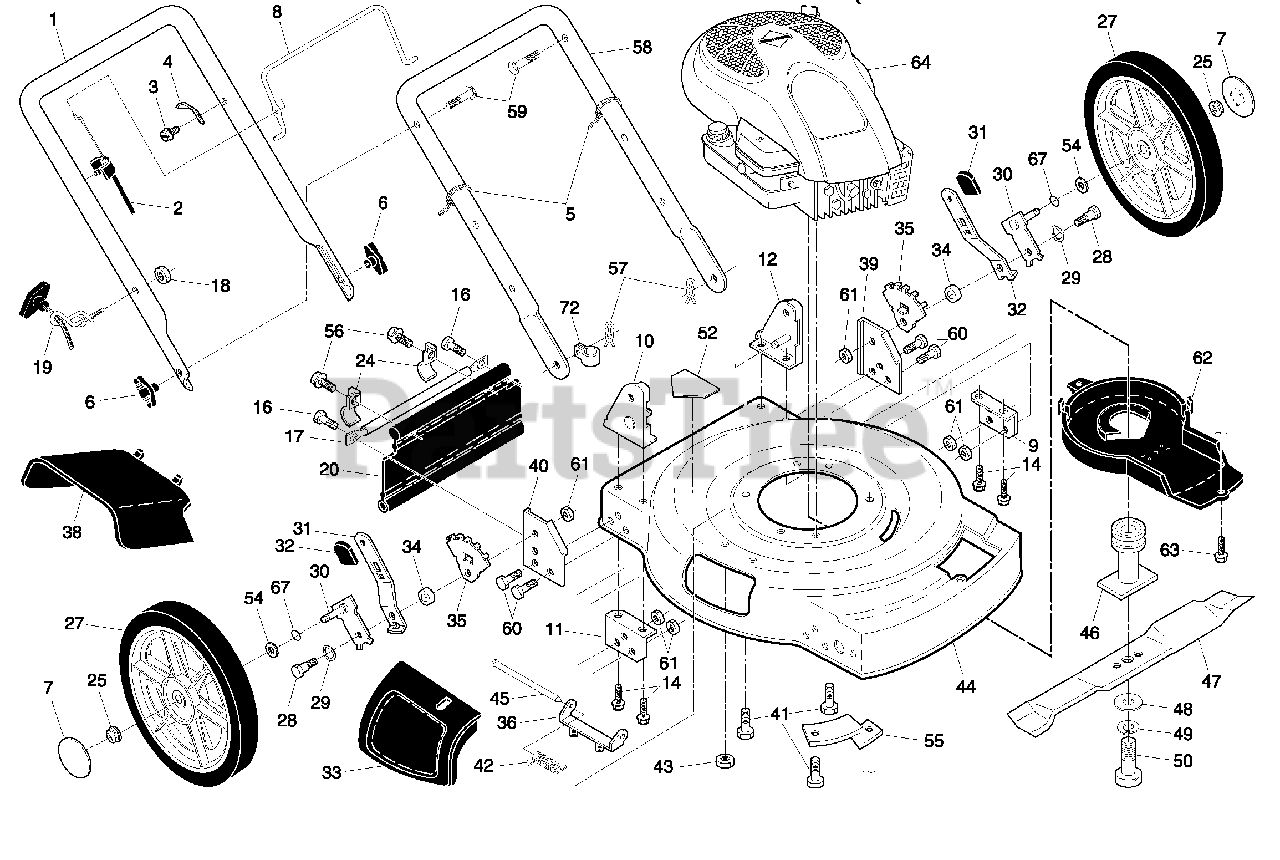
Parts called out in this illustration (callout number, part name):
1	Upper Handle
2	Engine Zone Control Cable
3	Screw
4	Bracket, Upstop
5	Wire Tie
6	Handle Knob
7	Hubcap
8	Control Bar
9	Support Bracket, Handle, LH
10	Handle Bracket, RH
11	Support Bracket, Handle, RH
12	Handle Bracket, LH
14	Screw, Thread Cutting 5/16-18 x 3/4
16	Screw
17	Support Rod
18	Locknut, Keps
19	Rope Guide
20	Rear Skirt
24	Clamp, Rear Skirt
25	Locknut, Hex 3/18-16
27	Wheel & Tire Assembly
28	Shoulder Bolt
29	Washer, Curved, Cylindrical
30	Axle Arm Assembly
31	Knob, Selector
32	Spring, Selector
33	Mulcher Door
34	Spacer
35	Bracket, Wheel Adjuster
36	Bracket, Housing
38	Deflector, Discharge
39	Support Bracket, LH
40	Support Bracket, RH
41	Screw, Hex Head, Threaded, Rolled 3/8-16 x 1-1/8
42	Spring, Torsion
43	Locknut, Hex
44	Kit, Lawn Mower Housing
45	Rod, Hinge
46	Blade Adapter / Pulley
47	Blade, 22"
48	Washer, Hardened
49	Washer, Lock, Helical
50	Screw, Hex Head, Grade 8 3/8-24 x 1-3/8
52	Decal, Danger
54	O-Ring
55	Mounting Bracket, Debris Shield
56	Screw, Hex Washer Head #10-24 x 1/2
57	Hairpin Cotter
58	Lower Handle
59	Handle Bolt
60	Bolt
61	Locknut, Hex
62	Debris Shield
63	Screw
67	O-Ring
72	Clip, Cable
72	Operator's Manual, English
72	Operator's Manual, French
72	Repair Parts Manual
